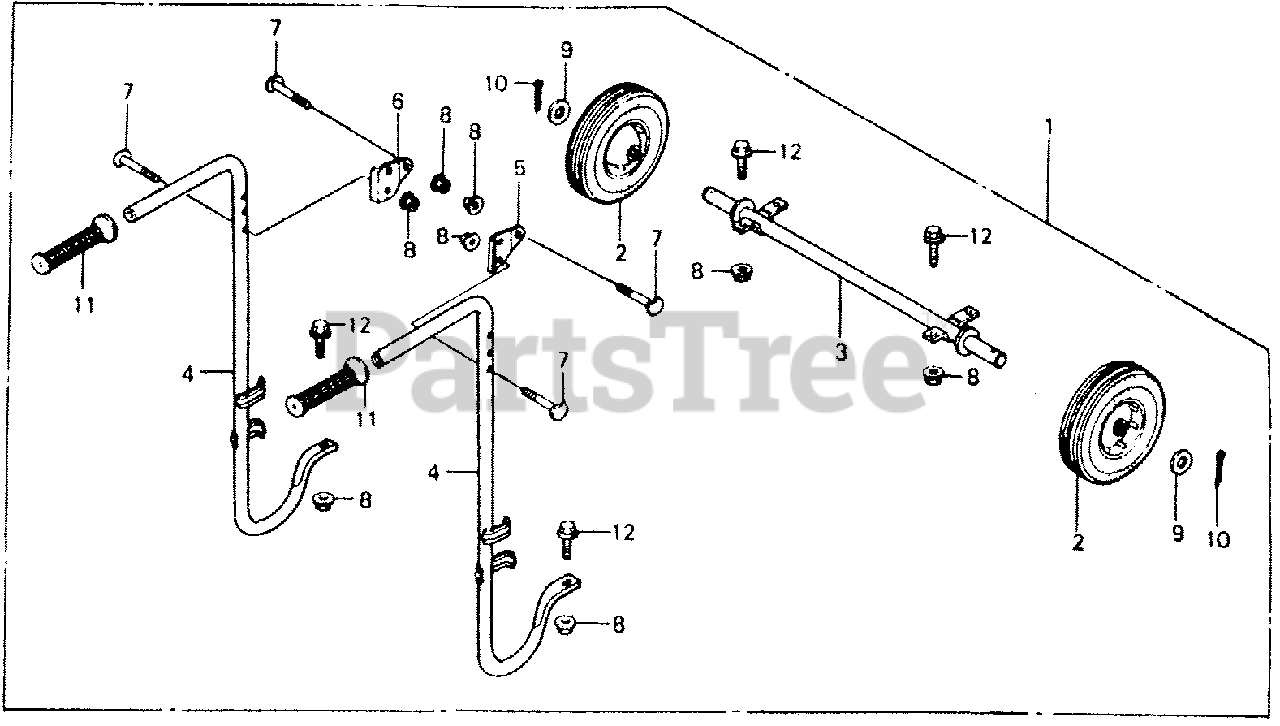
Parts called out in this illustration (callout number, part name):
1	WHEEL KIT (2-WHEELS)
2	WHEEL (10"X2.75")
3	SHAFT, WHEEL
4	HANDLE, CARRY
5	HOLDER, R. HANDLE
6	HOLDER, L. HANDLE
7	BOLT, HANDLE HOLDER
8	NUT, FLANGE (8MM)
9	WASHER, FLAT (20MM)
10	PIN, COTTER (4.0X30)
11	GRIP, R. HANDLEBAR
12	BOLT, FLANGE (8X16)
